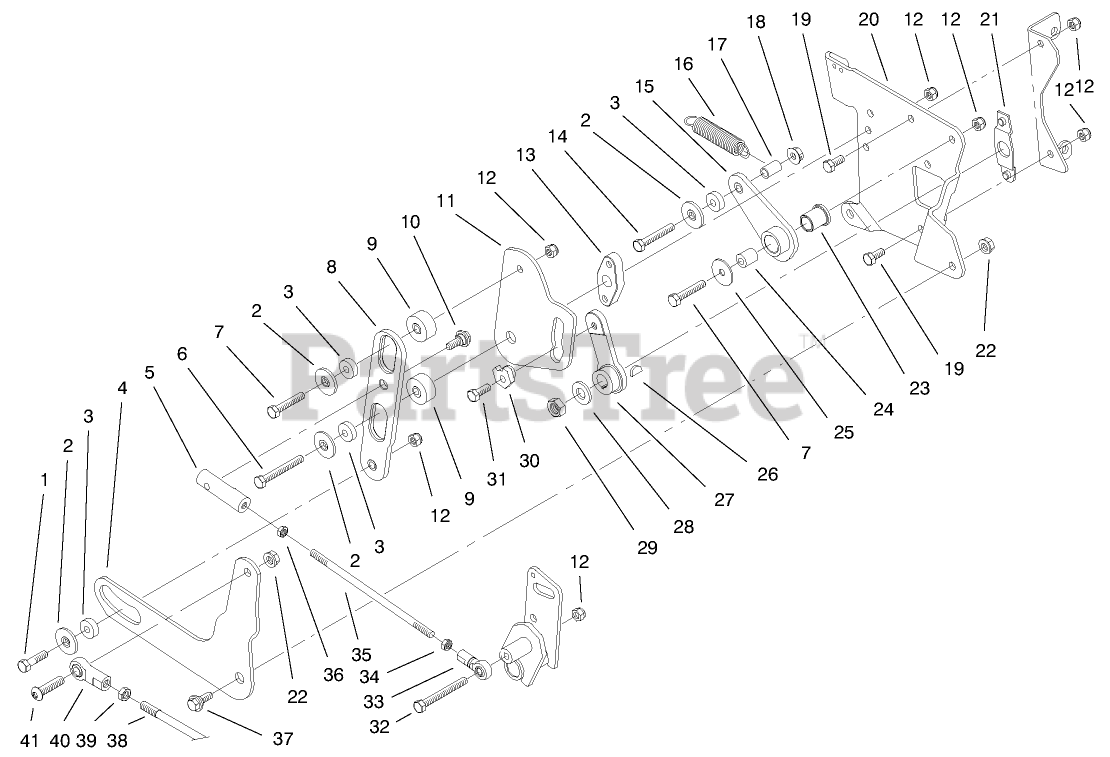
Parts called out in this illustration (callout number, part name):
1	SCREW-HH
2	RETAINER-BEARING
3	BEARING-BALL
4	SLIDER-LIFT
5	END-ROD, RH
6	SCREW-HH
7	SCREW-HH
8	SLIDER-CONTROL, SPEED
9	STANDOFF-CAM PLATE
10	BOLT-SHOULDER
11	PLATE-CAM
12	NUT-LOCK, NI
13	STANDOFF-SLIDER
14	SCREW-HH
15	ARM-RETURN TO NEUTRAL
16	SPRING-IDLER
17	STANDOFF-SPRING
19	SCREW-HH
20	PLATE-CONTROL
21	LOCATOR-CONTROL PLATE
22	NUT-HEX
23	BUSHING-FLANGED
24	SPACER
25	WASHER-FLAT
26	KEY-WOODRUFF
27	ARM-CONTROL, SPEED
28	WASHER-FLAT
29	NUT-HEX
31	SCREW-THREAD LOCKING
32	SCREW-HH
33	END-ROD, RH
34	NUT-JAM
35	ROD-SLIDER TO PIVOT
36	NUT-JAM
37	BOLT-SHOULDER
38	ROD-LIFT
39	NUT-HJ
40	END-ROD, FEMALE
41	SCREW-HSBH
